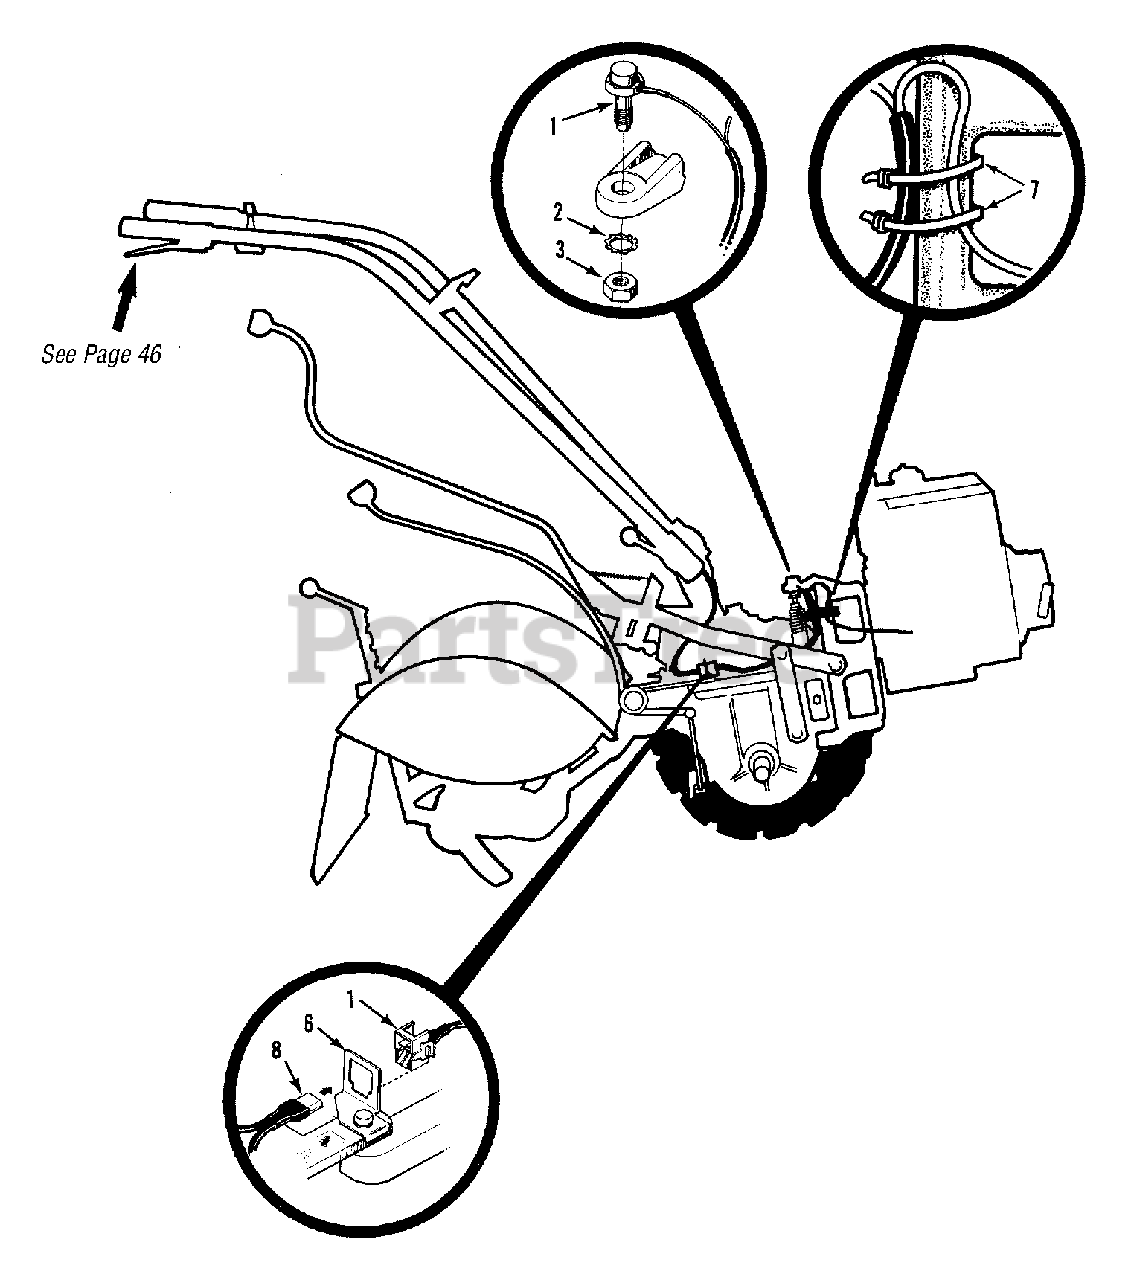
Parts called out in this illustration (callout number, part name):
1	Engine Wire Harness Assy-forward interlock system
2	Lockwasher-external tooth, 7/16"
3	Nut-hex, 7/16"-20
6	Clip-for plug connector
7	Tie-plastic
8	Handlebar Wire Harness Assy
